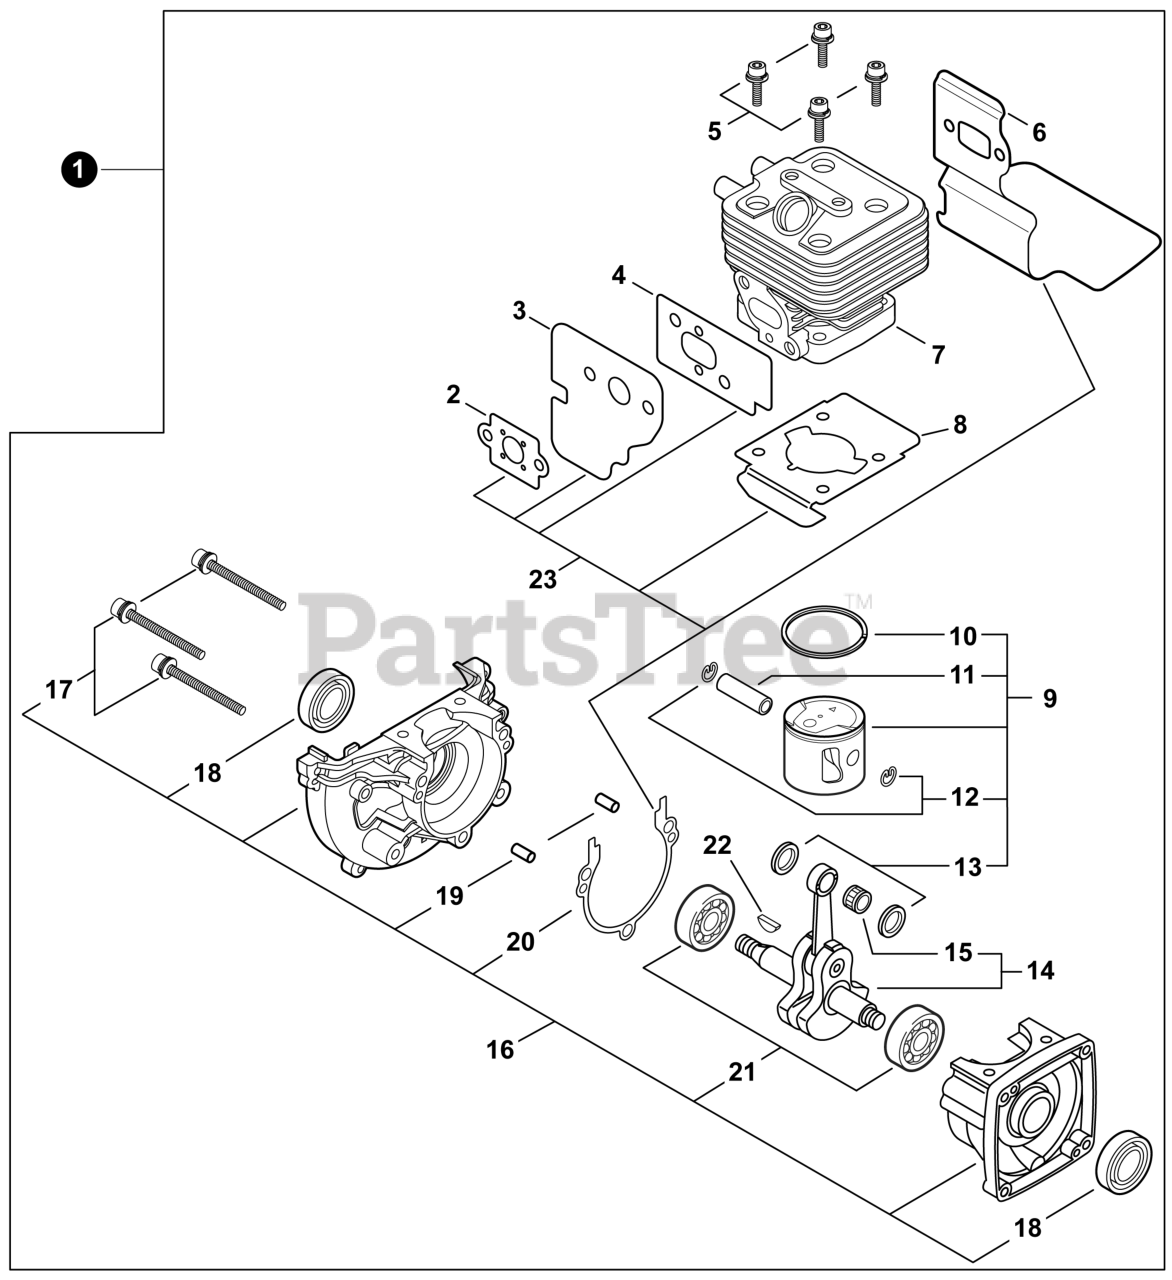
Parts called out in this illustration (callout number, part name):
1	SHORT BLOCK
2	GASKET, INTAKE
3	GASKET, INTAKE
4	GASKET, INTAKE
5	BOLT 5×25
6	HEAT SHIELD, EXHAUST
7	CYLINDER
8	GASKET, CYLINDER
9	PISTON KIT
10	RING, PISTON
11	PIN, PISTON
12	RING, SNAP
13	WASHER, THRUST
14	CRANKSHAFT ASSY
15	BEARING, NEEDLE 8
16	CRANKCASE KIT
17	BOLT 5×28
18	SEAL, OIL 12
19	PIN, LOCATING 4×8
20	GASKET, CRANKCASE
21	BEARING, BALL 6201
22	KEY, WOODRUFF
23	GASKET KIT
